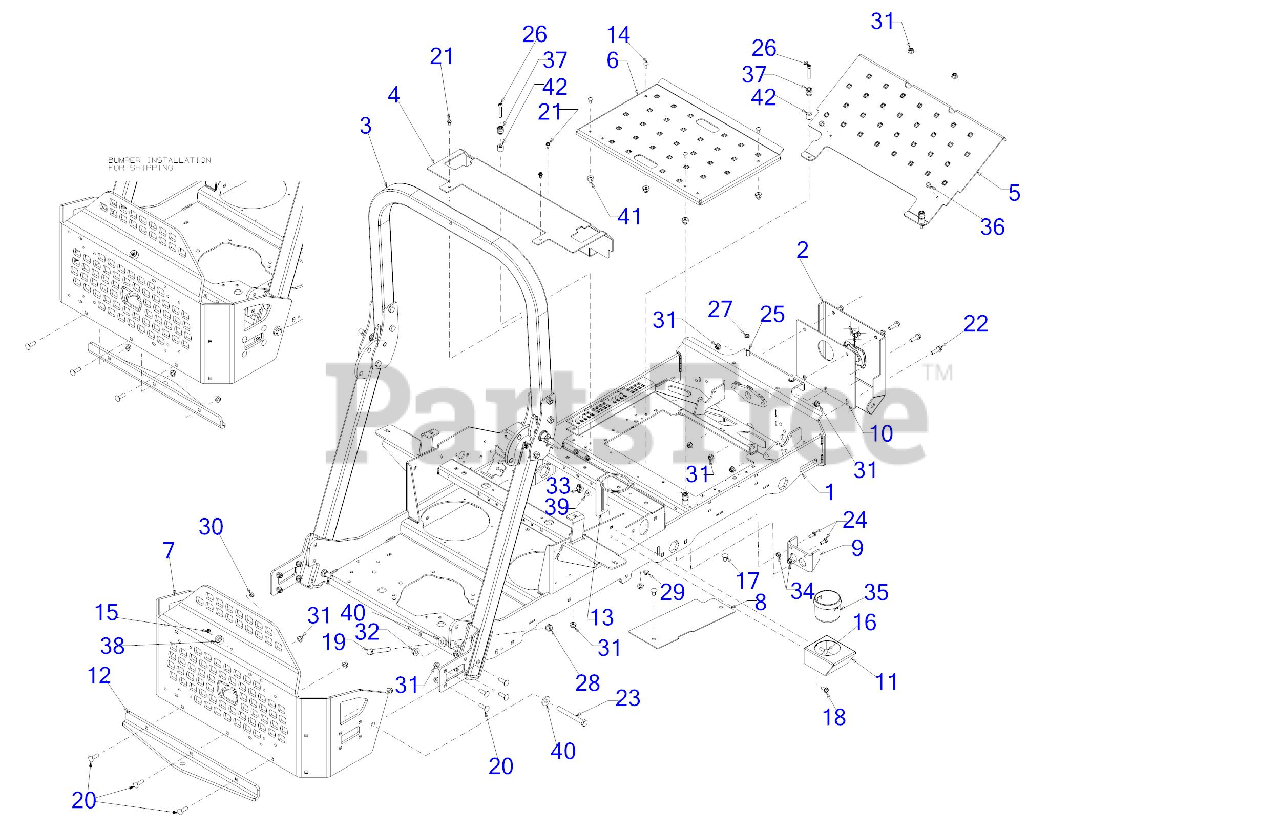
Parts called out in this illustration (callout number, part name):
3	ROPS
14	CARRIAGE BOLT 1/4-20 x .62
15	MACHINE SCREW 1/4-20:1
16	CARRIAGE BOLT 5/16-18 x 1.00
17	CARRIAGE BOLT 3/8-16 x .750 GR5
18	SCREW 5/16-18 x .750
19	SCREW 1/2-20 x 3.50 GR5
20	CARRIAGE BOLT 3/8-16 X1.25 GR5
21	SCREW 1/4-20 X.500
22	SCREW 3/8-16 x 1.25 GR5
22	FLAT WASHER
23	SCREW 1/2-13 x 4.5 GR 5
24	SCREW 5/16-18 x .75 GR5
25	CARRIAGE BOLT 3/8-16 x 1.00 GR5
26	SCREW 5/16-18X1.75 GR5
28	HEX NUT
29	FLANGE LOCK NUT 5/16-18
30	FLANGE LOCK NUT
33	WING NUT 5/16-18
34	FLANGE NUT
36	BUMPER, .62 DIA x .3
37	RADIAL BUMPER
39	FLAT WASHER
40	FLAT WASHER .531 x 1.25 x .181
41	SHOULDER SPACER
